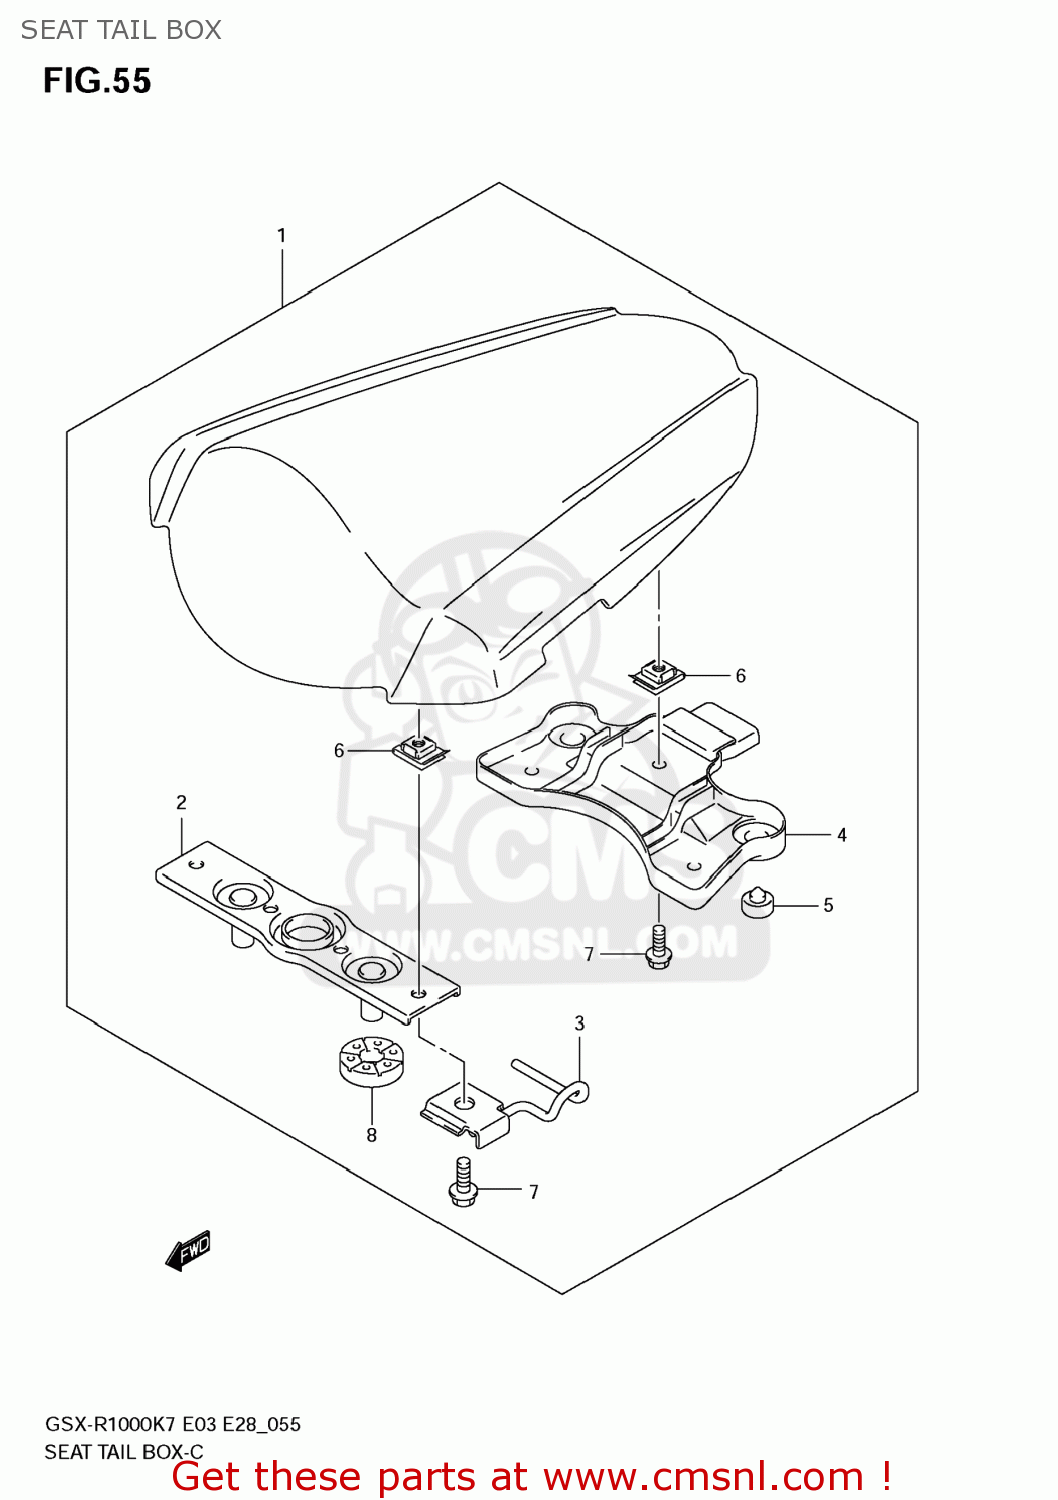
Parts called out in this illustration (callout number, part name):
1	BOX,SEAT TAIL(BLUE)
2	SLOT. BUDDYKAP
3	HOLDER,HELMET
4	BOTTOM,SEAT TAIL BOX
5	CUSHION
6	NUT
7	BOLT
8	CUSHION
